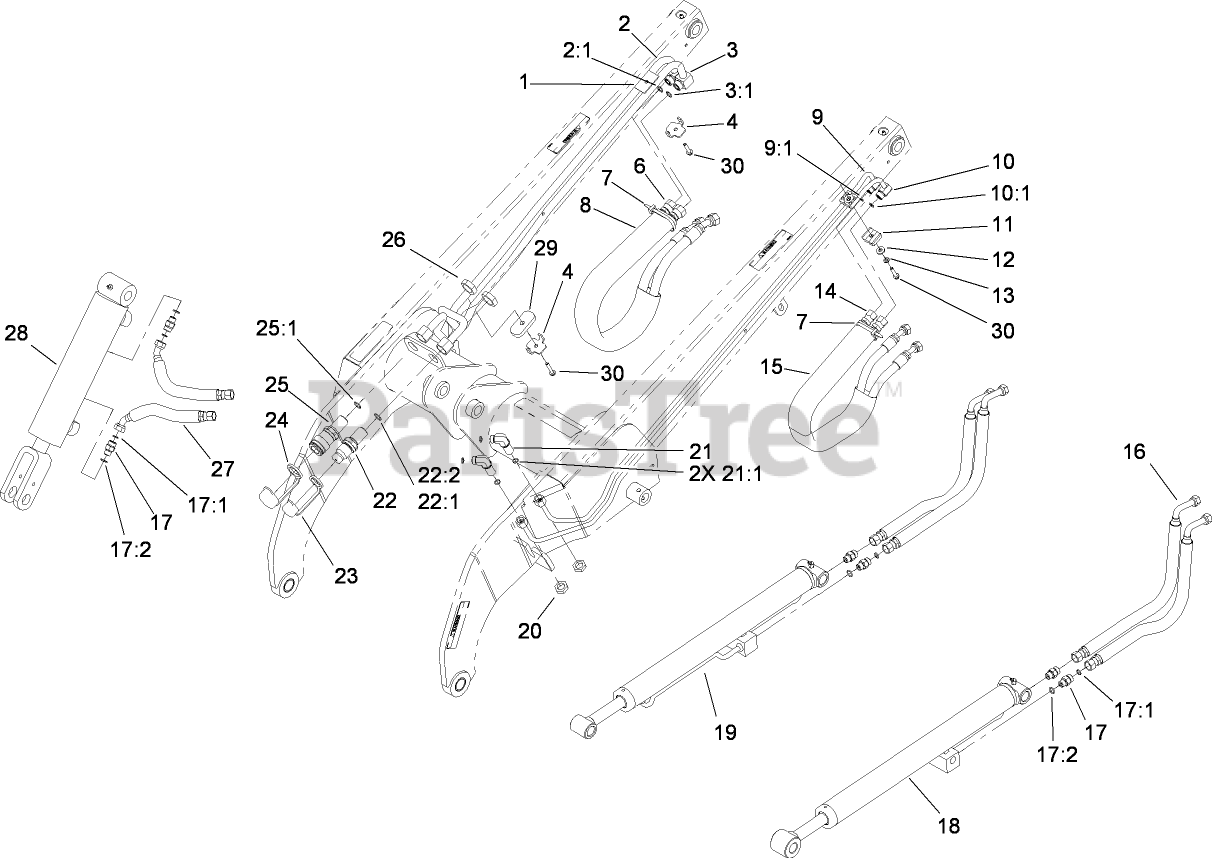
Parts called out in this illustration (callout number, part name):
1	SPACER-HARDLINE
2	HYD TUBE ASM
2:1	O-RING
3	HYD TUBE ASM
3:1	O-RING
4	PLATE-CLAMP, TUBE
6	HOSE-HYD
7	TIE-CABLE
8	SLEEVE-PROTECTIVE
9	HYD TUBE ASM
9:1	O-RING
10	HYD TUBE ASM
10:1	O-RING
11	CLAMP-TUBE
12	WASHER-FLAT
13	WASHER-LOCK
14	HOSE-HYD
15	SLEEVE-PROTECTIVE
16	HOSE-HYD
17	FITTING-STRAIGHT
17:1	O-RING
17:2	O-RING
18	LH LIFT CYLINDER ASM
19	RH LIFT CYLINDER ASM
20	NUT-LOCK
21	UNION-BULKHEAD
21:1	O-RING
22	BULKHEAD NIPPLE ASM
22:1	O-RING
23	CAP-DUST, NIPPLE
24	CAP-DUST, COUPLER
25	BULKHEAD COUPLER ASM
25:1	O-RING
26	NUT-LOCK, BULKHEAD
27	HOSE-HYD
28	TILT CYLINDER ASM
29	PLATE-HARDLINE
30	SCREW-HWH
